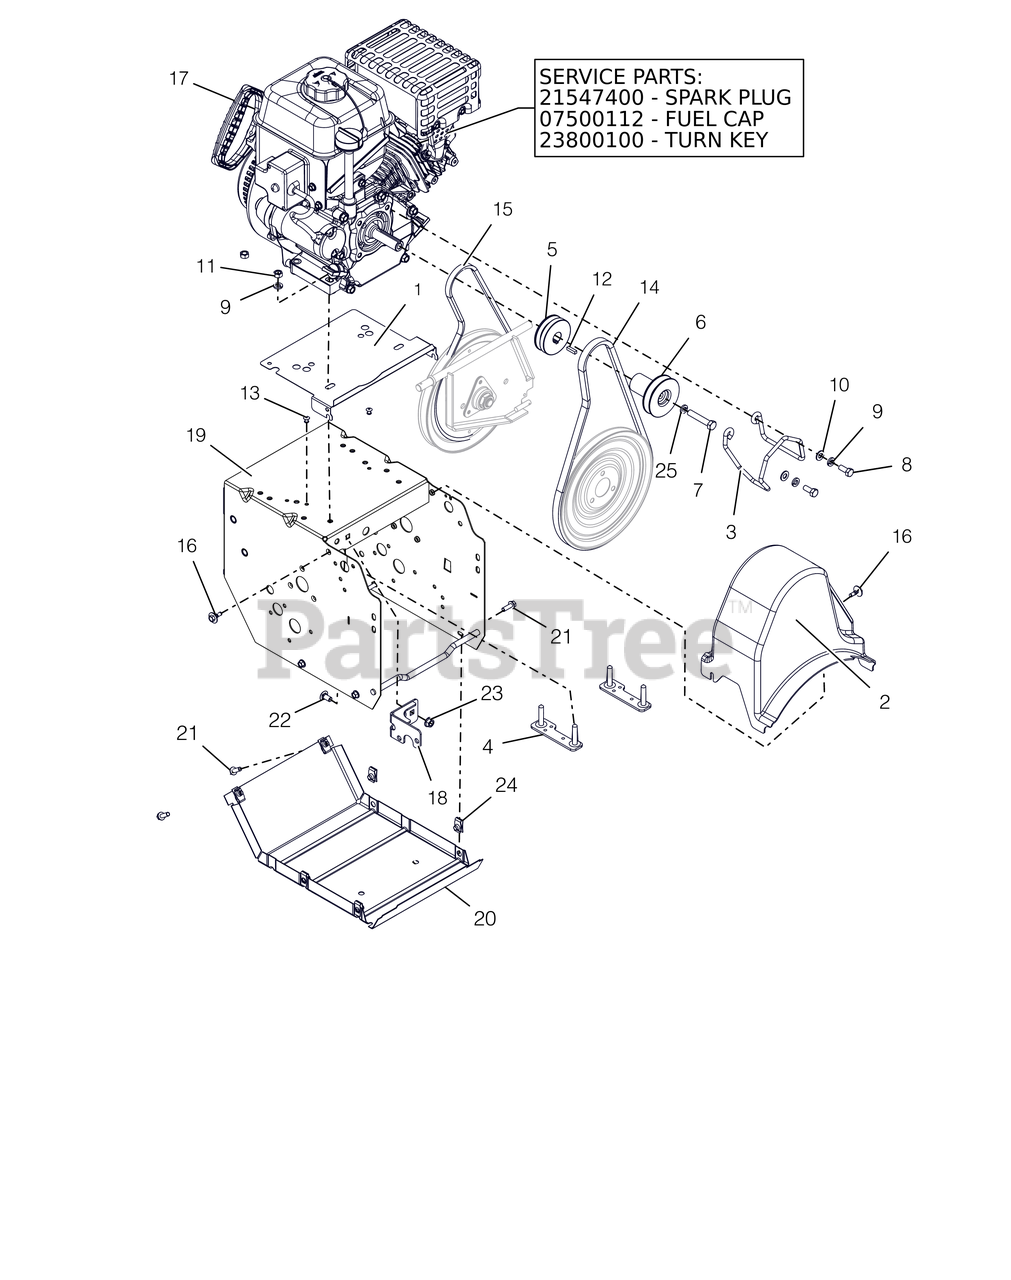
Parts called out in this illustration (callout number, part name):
1	BAFFLE, COMPACT
2	COVER, COMPACT BELT
3	FINGER, BELT
4	STRAP, ENGINE BOLT-WELDMENT
5	SHEAVE, TRACTION-COMPACT TRACK
6	SHEAVE,AUGER 3/4" PM
7	BLT-HEX .38-24X2.0 YWZC
8	BLT-HEX .31-24X.75 YWZC GR5
9	WSHR-LK .312X.097 HVY YWZC
10	@WSHR-FL-STL.344X.688X.065YWZC
11	@NUT-HEX .31-18 YWZC
12	KEY-SQ .188X.75X.188
13	RVT-POP .187 YZ
14	V-BELT, HA-RAW EDGE
15	V-BELT, 3L-WRAPPED
16	SCR-TAP .25-20X.5 CAPTIVE
17	ENGINE, AX223 GEN 2 120V/60W
17	PLUG, SPARK
17	CAP, FUEL TANK BLACK
17	KEY, TURN LCT (2/PACKAGE)
18	WELDMENT, FRAME BRACKET
19	FRAME, MAIN-WELDMENT
20	COVER, BOTTOM
21	BLT-HEX .25-20X.75 HWH YZ GR5
22	@BLT-RHDSSQNK .31-18X.62 G5YZ
23	@NUT-LK-TOP-FLG .31-18 YWZC
24	NUT-RTNR .25-20X.56
25	WSHR-LK .312X.097 HVY YWZC
